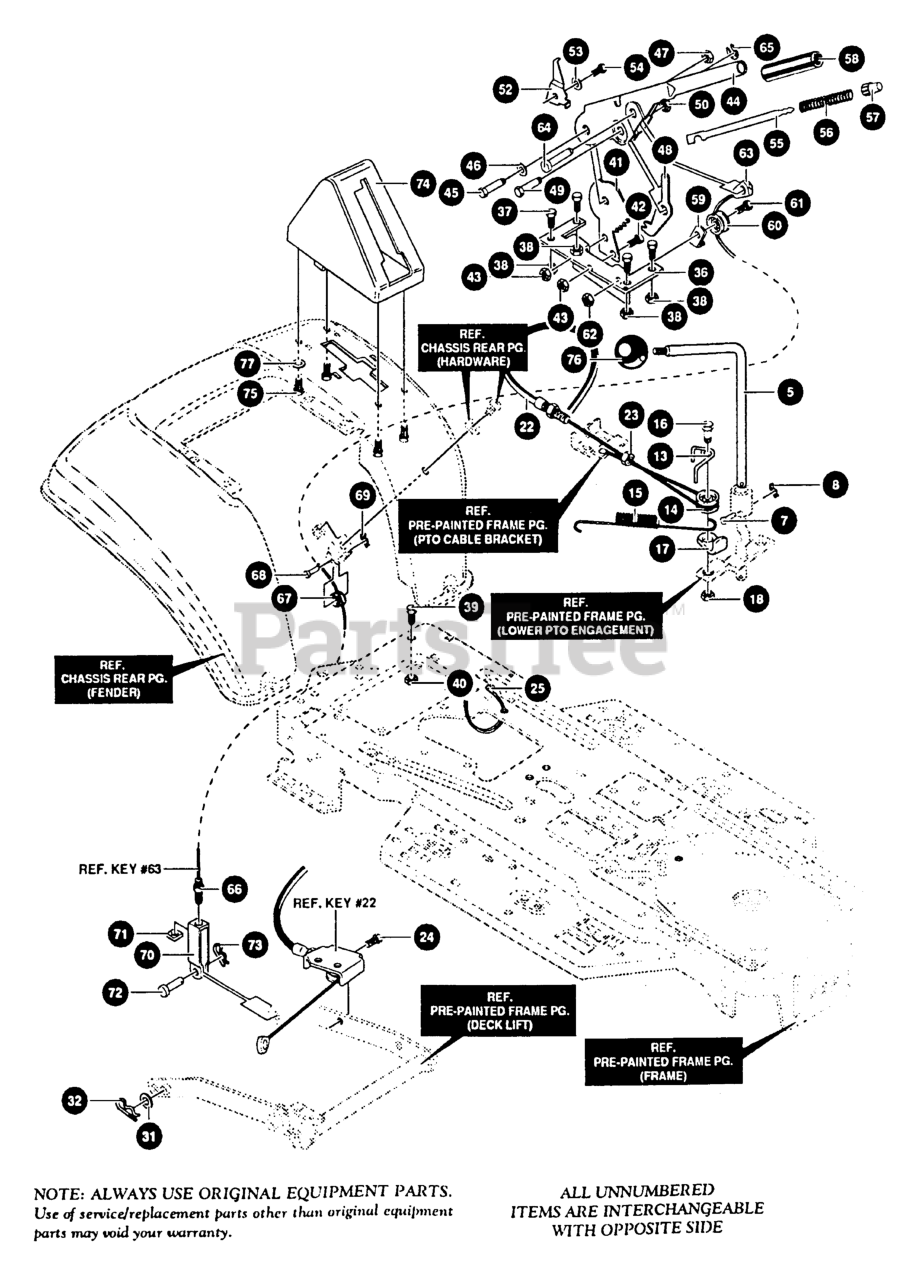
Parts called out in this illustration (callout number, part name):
5	LEVER, PTO UPPER
7	PIN, CLEVIS .25D X 1.094
8	PIN, HAIR
12	ASSEMBLY, CABLE PTO ENGAGE
13	SPRING, CABLE KEEPER
14	PULLEY, METAL
16	BOLT, .375 X .565
17	BRACKET, CABLE RETAINER
18	NUT, 1/4-20
23	NUT, 1/4-28
24	SCREW, 5/16-18 x 0.62
25	TIE, CABLE
31	WASHER, FLAT .531 X 1.06 X .063
32	PIN, HAIR
36	BRACKET, HEIGHT ADJUST
37	SCREW, 5/16-18 x 0.75
38	NUT, 5/16-18
39	SCREW, 5/16-18 x 0.75
40	NET, 5/16-18
41	QUADRANT, HEIGHT ADJUST
42	SCREW, 5/16-18 x 0.75
43	NUT, 5/16-18
44	HANDLE, LIFT SHORT
45	BOLT, .500 X .170
46	WASHER, FLAT .506 X .75 X .024
47	NUT, 5/16-18
48	PAWL, SQUARE
49	BOLT, .500 X .270
50	NUT, 5/16-18
52	POINTER, HEIGHT ADJUST
53	WASHER, .195 X .41 X .03
54	SCREW, #8-32 X .38
55	ROD, ACTUATOR-SHORT
56	SPRING, HEIGHT ADJUST
57	KNOB, HEIGHT ADJUST
58	GRIP, W/ HOLE BLACK
59	BRACKET, CABLE RETAINER
60	PULLEY, METAL
61	BOLT, .375 X .375
62	NUT, 1/4-20
63	ASSEMBLY, CABLE LIFT
64	PIN, CLEVIS
65	RING, RET E
66	NUT, 1/4-20
67	PULLEY, METAL
68	PIN, CLEVIS
69	PIN, HAIR
70	CLEVIS, LIFT CABLE
71	NUT, 1/4-20
72	PIN, CLEVIS
73	PIN, COTTER
74	LIFT COVER
75	SCREW, #10 X .75
77	WASHER, FLAT .281 X .63 X .065
